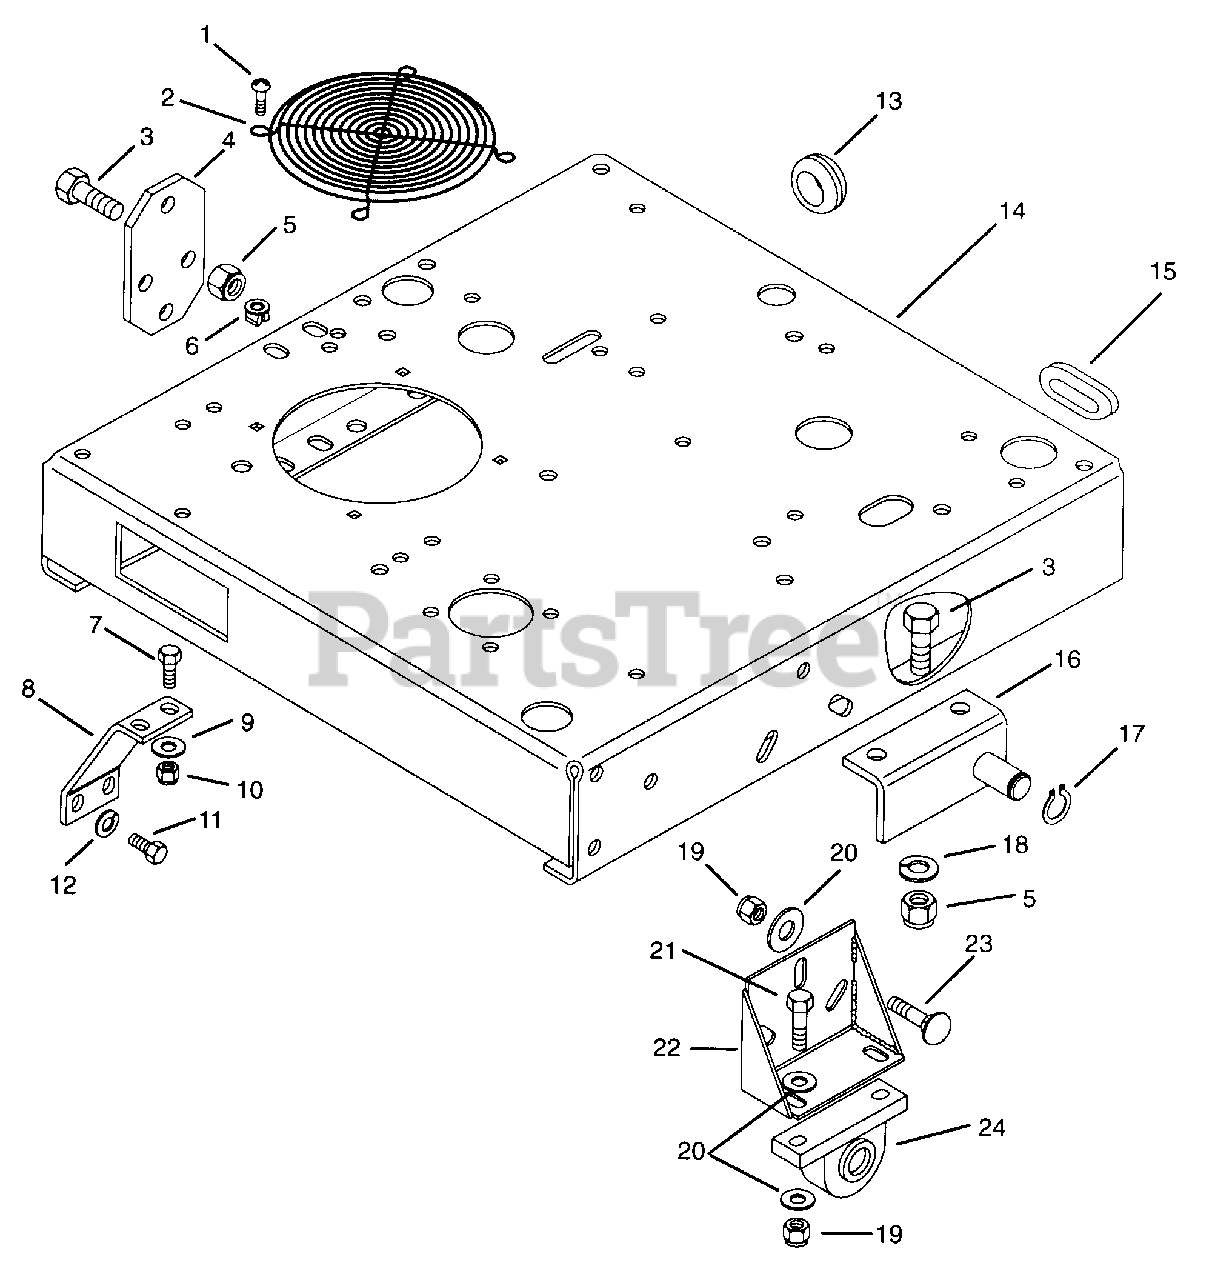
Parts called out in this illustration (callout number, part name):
1	Screw-Tapping .25-20 x .50
2	Guard Fan
3	Bolt-Hex .50-13 x 1.50 Grade 5
4	Plate
5	Nut-Locking-Nylon .50-13
6	Grommet, Plastic
7	Bolt-Hex .31-18 x 1.00 Grade 5
8	Bracket, Transaxle Support
9	Washer-Flat-Steel .344 x .688 x .065
10	Nut-Locking-Nylon .312-18
11	Bolt-Hex .31-18 x .75 Grade 5
12	Washer-Lock .313 x .078
13	Grommet 1.50 x 1.75 x 2.12
14	Weldment, Frame
15	Grommet .63 x .687 x 1.25
16	Weldment, Pivot Left Hand
16	Weldment, Pivot Right Hand
17	Ring-Retaining-External .689 x .077
18	Washer-Lock .50
19	Nut-Locking-Nylon .375-16
20	Washer-Flat-Steel .406 x .812 x .065
21	Bolt-Hex .38-16 x 1.50 Grade 5
22	Weldment, Axle Support
23	Bolt-Round Head Square Neck .38-16 x 1.00
24	Bearing, Pillow Block 1.0 x 2.688 x 6.188
